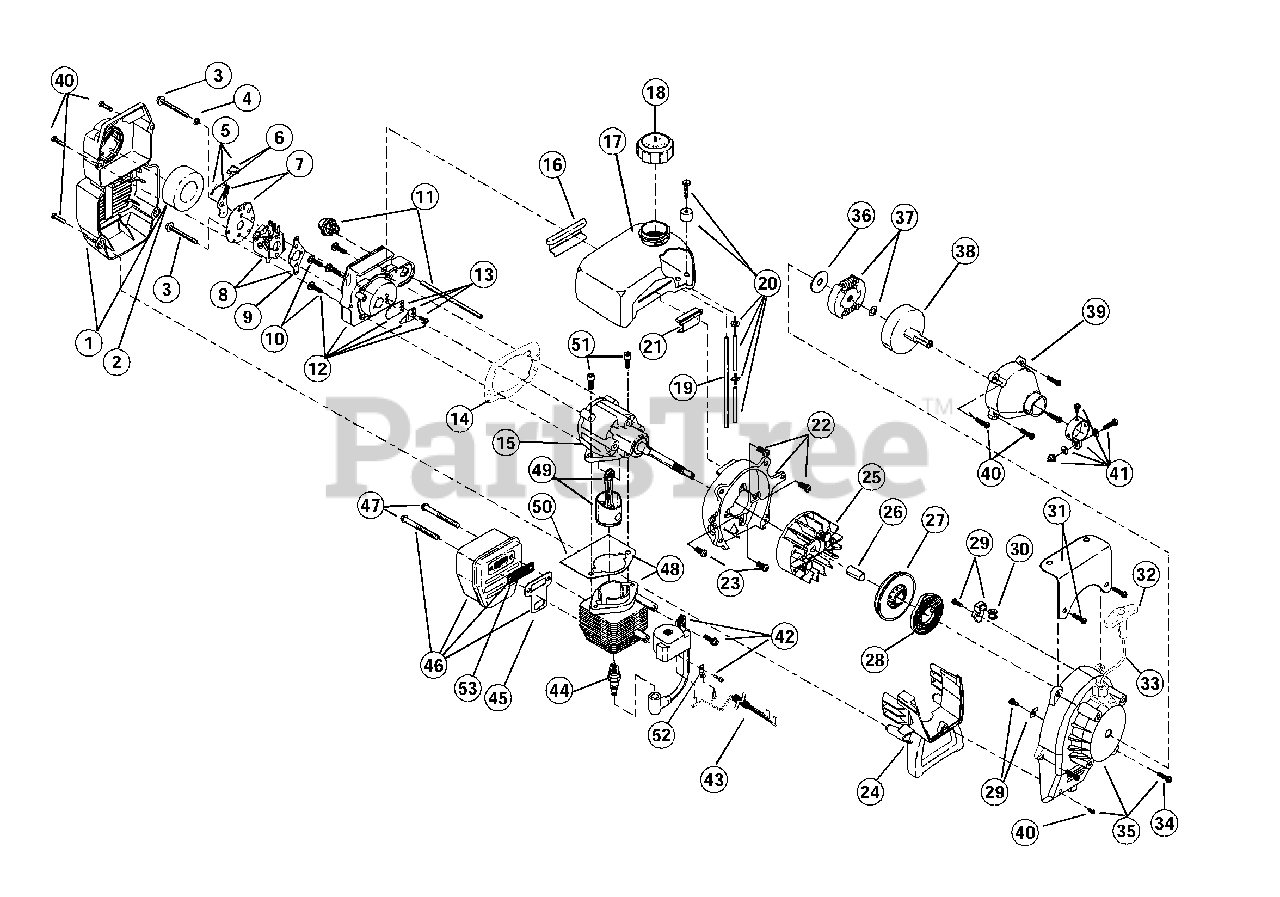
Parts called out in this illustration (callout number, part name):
1	Air Cleaner/Muffler Cover Assembly
2	Air Cleaner Filter
3	Carburetor Mounting Screw Assembly
4	Wavey Washer
5	Choke Lever Assembly
6	Choke Knob and Screw
7	Choke Lever and Plate
8	Carburetor Assembly
9	Carburetor Gasket
10	Carb Mount Screw
11	Primer and Hose Assembly
12	Carb Mount Assembly
13	Reed Assembly
14	Carburetor Mount Gasket
15	Crank Case Service Assembly
16	Rear Mounting Pad
17	Fuel Tank Assembly
18	Fuel Cap Assembly
19	Fuel Return Line
20	Fuel Line Assembly
21	Front Mounting Pad
22	Shroud Assembly
23	Shroud Screw
24	Shroud Extension and Stand
25	Flywheel Assembly
27	Recoil Pulley Assembly
28	Recoil Spring
29	Pulley Retainer Assembly
30	Rope Guide
31	Fuel Tank Guard Assembly
32	Pull Handle
35	Starter Housing Assembly
36	Clutch Washer
37	Clutch Rotor Assembly
38	Clutch Drum Assembly
39	Clutch Cover Assembly
41	Upper Clamp Assembly
42	Module Assembly
43	Wire Lead
44	Spark Plug
45	Exhaust Gasket
46	Muffler Assembly
47	Muffler Mounting Bolt Assembly
48	Cylinder Assembly
49	Piston and Rod Assembly
50	Cylinder Gasket
51	Cylinder Bolt
52	Ground Tab
53	Spark Arrestor
